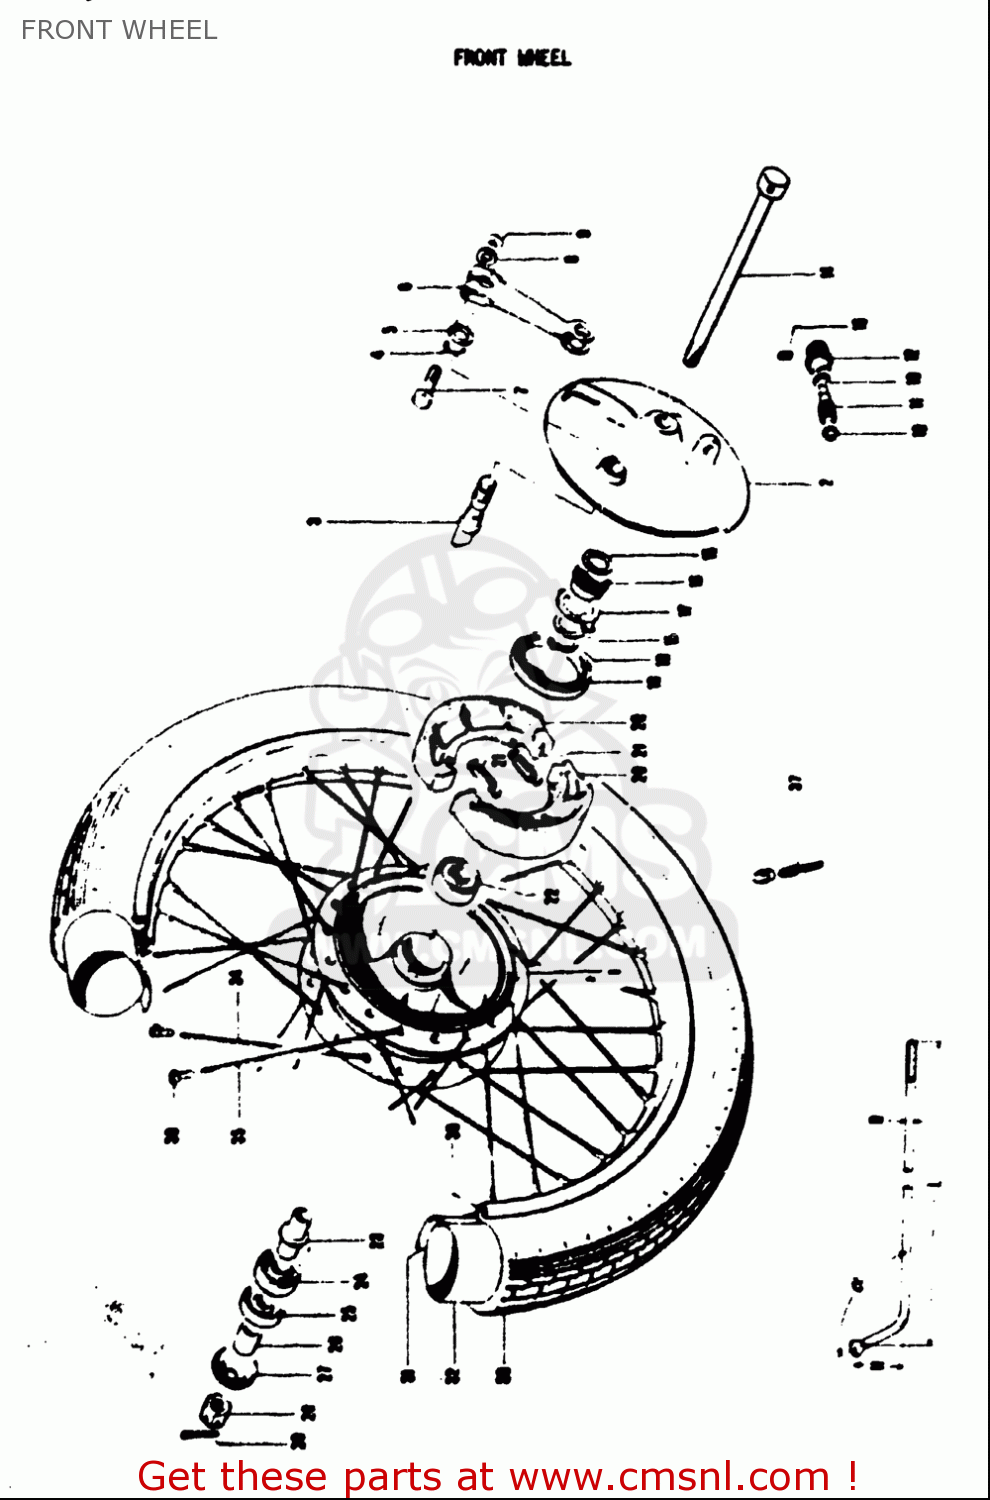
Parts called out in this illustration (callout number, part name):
4	O RING(D:2.5,ID:11.4)
5	WASHER(12.5X20X1)
7	BOLT(6X31)
8	WASHER
9	NUT
10	WASHER(5.1X9X0.4)
13	SCREW
14	AXLE,FR
15	WASHER(18.5X24X1)
17	DRIVER,SPEEDOMETER GEAR
18	CIRCLIP
21	SPRING(L:35.8)
22	BEARING
24	BEARING
25	OIL SEAL(17X38X5)
26	SPACER(12X18X19.4)
28	NUT 12MM
29	PIN
30	RIM,WHEEL(1.40X18)
31	PROTECTOR,INNER TUBE
33	SPOKE SET,FR
